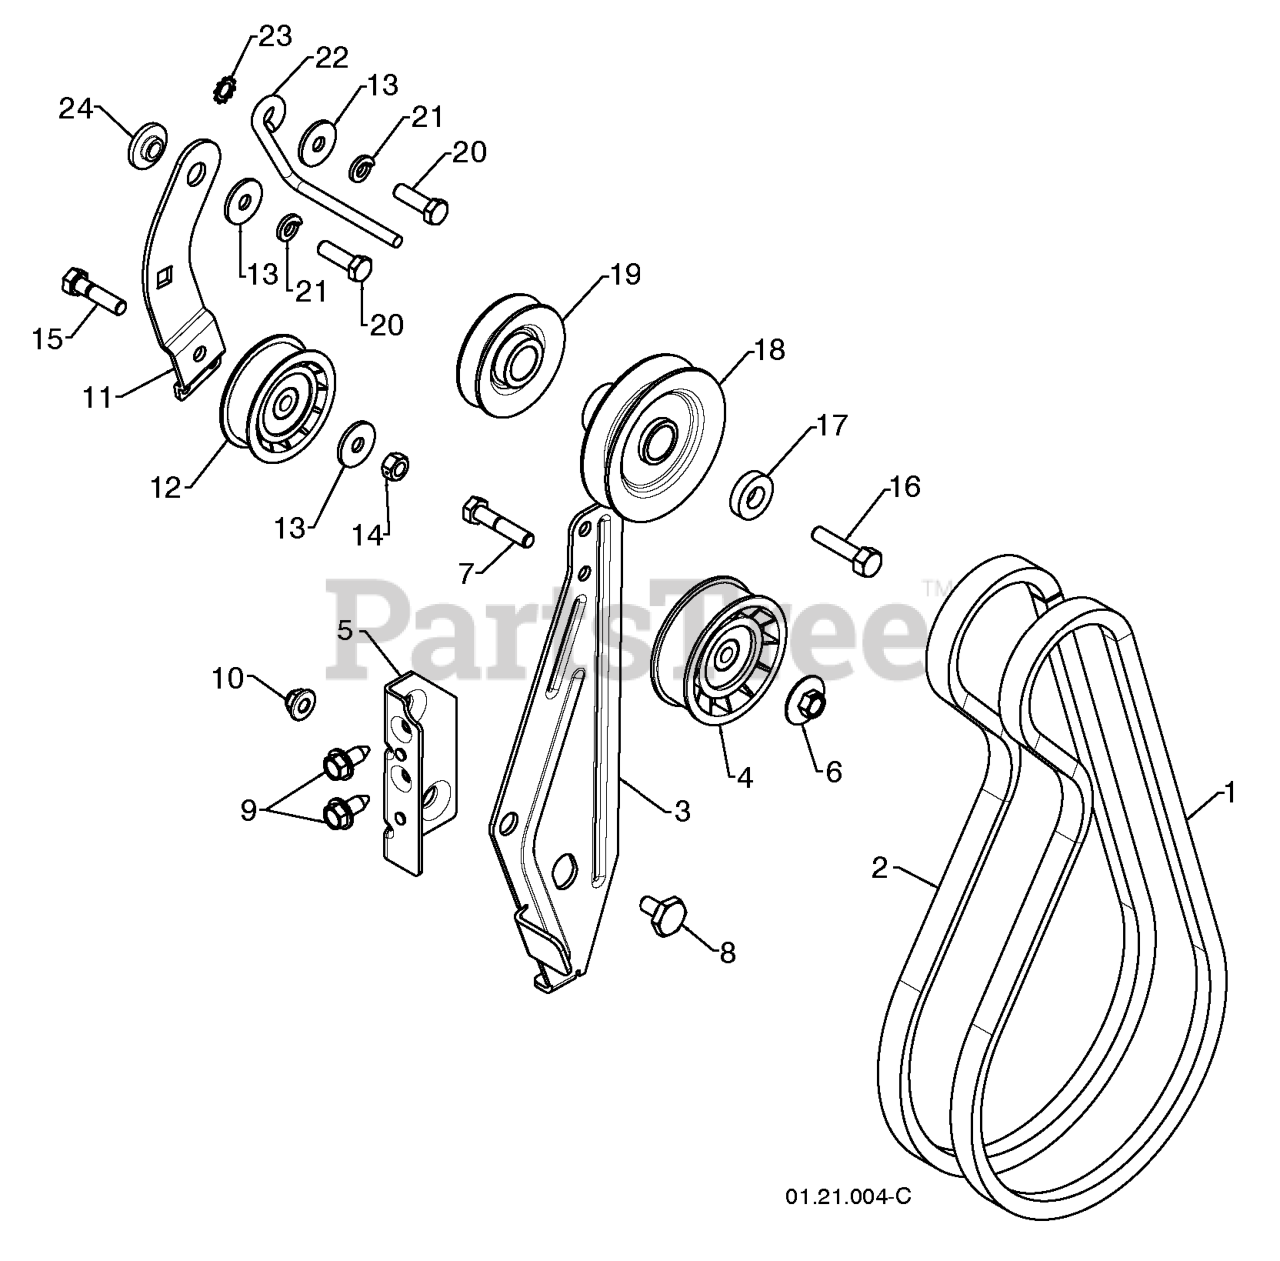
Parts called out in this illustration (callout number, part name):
1	VBELT; IMPELLER_39.09
2	V-BELT TRACTION 34.25
3	ARM.IDLER.BRAKE
4	PULLEY.IDLER.W/SPACER.
5	RP BRACKET.IDLER
6	NUT.FLANGE.HEX.5/16X18.BLACK
7	HEX BOLT
8	BOLT.SHOULDER.1/2X12
9	BOLT.HEX.HD.WASHER.5/16-18X.75
10	NUT.LOCK.5/16-18
11	ARM, IDLER
12	PULLEY.W/SPACER.2.25
13	STEEL WASHER
14	NUT.71038.31-18.HEX.NYLOCK
15	BOLT.5/16-18X1-1/4 FULL.THREAD
16	SCREW, HEX HD 3/8-24 X 1-3/8
17	WASHER, FLAT 3/8
18	PULLEY.ENG.IMPELLER.SNOW
19	PULLEY.ENG.TRACTION
21	WASHER.LOCK.HVY.HLCL.SPR.5/16
22	BELT.GUIDE.RH
23	WASHER EXT TOOTH LOCK 5/16
24	RP BUSHING, IDLER PIVOT
